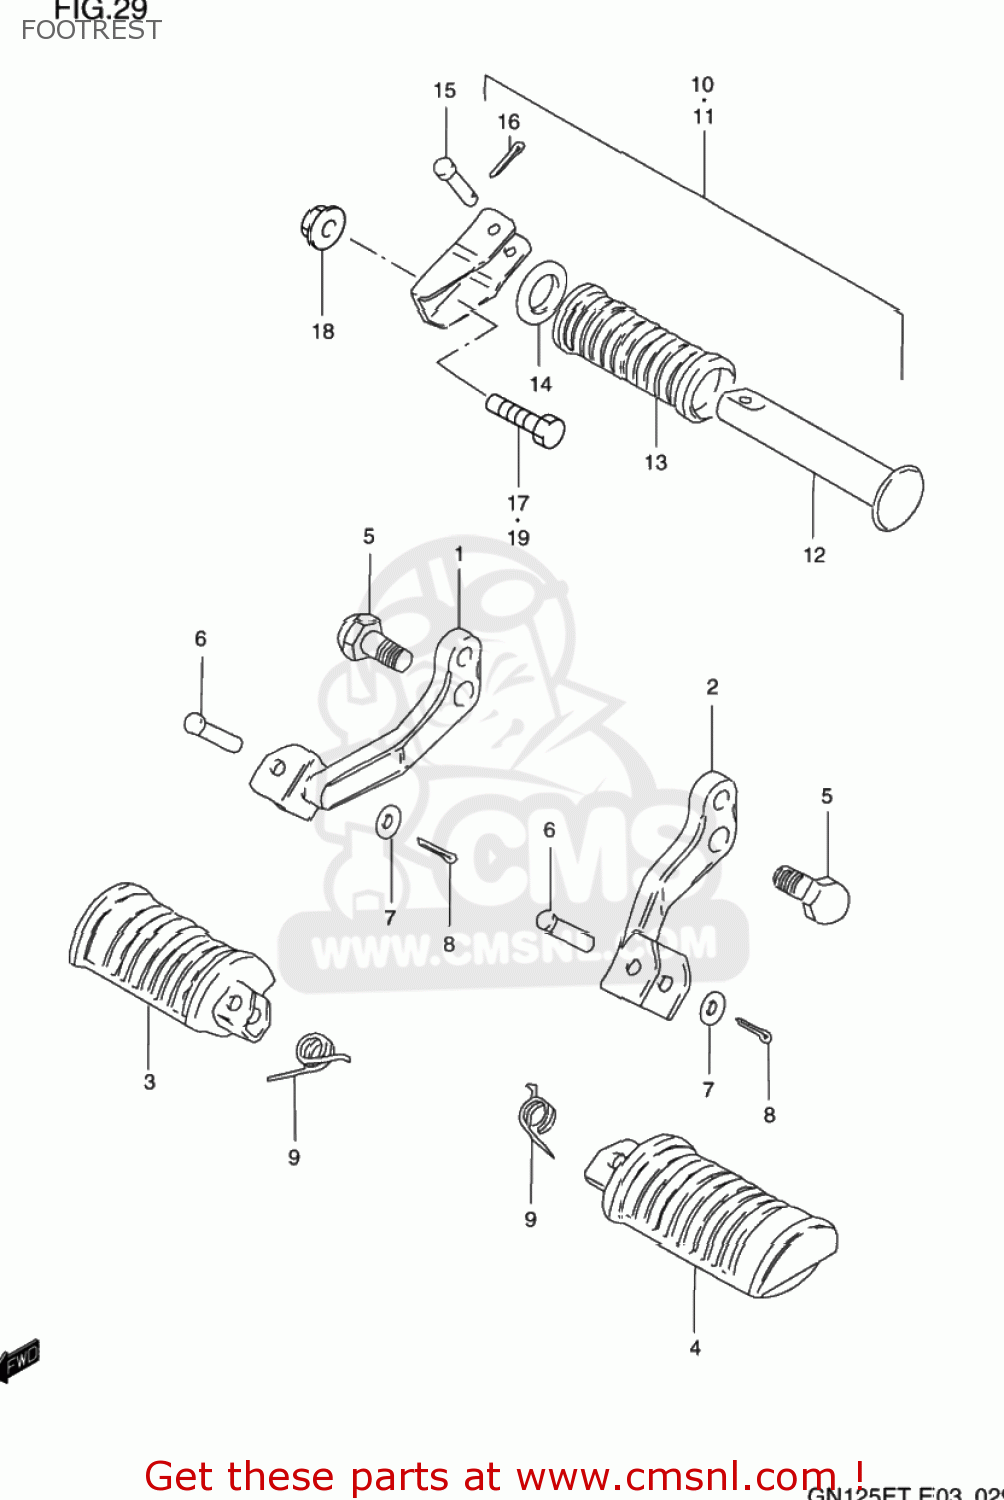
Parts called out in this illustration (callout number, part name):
1	HOLDER,FR FOOTREST,R
2	HOLDER,FR FOOTREST,L
3	RUBBER,PILLION FOOTREST,R
4	RUBBER,PILLION FOOTREST,L
5	BOLT
6	PIN
7	WASHER
8	PIN 20X20
9	SPRING
10	FOOTREST ASSY,PILLION,R
11	FOOTREST ASSY,PILLION,L
12	BAR,FOOTREST RUBBER
13	RUBBER,PILLION FOOTREST
14	WASHER (19.5X32X2)
15	PIN
16	PIN
17	BOLT
18	NUT
19	BOLT
